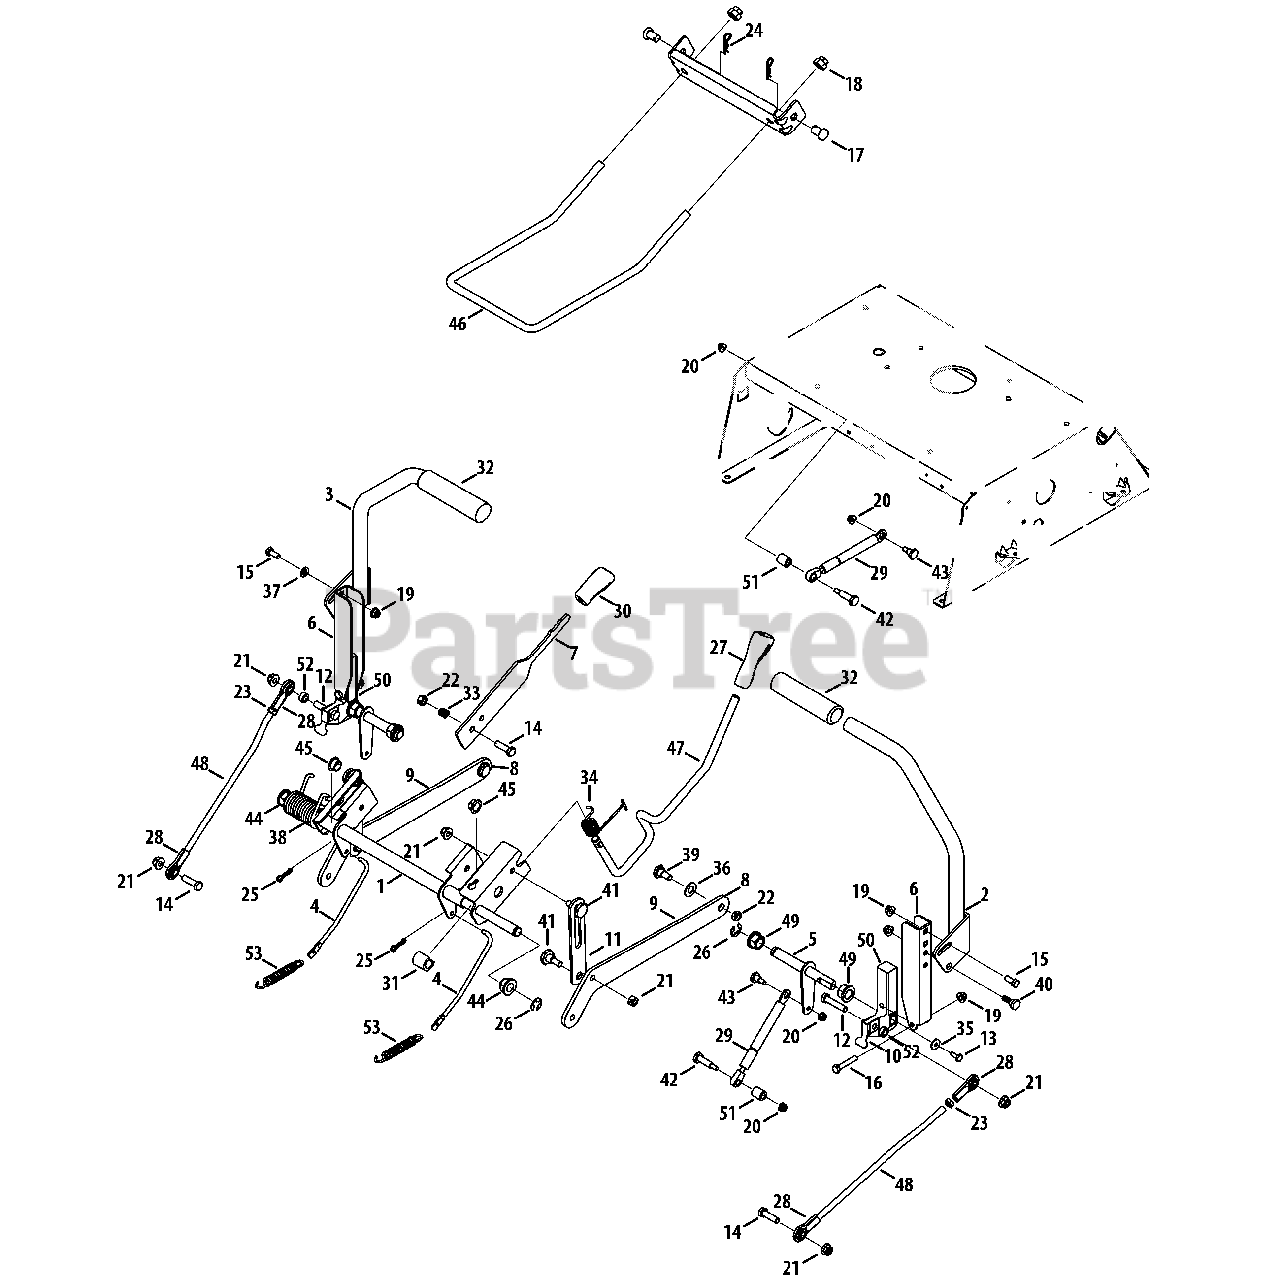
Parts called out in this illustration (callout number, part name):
1	Deck Lift Shaft Assembly
2	Lapbar Lever RH
3	Lapbar Lever LH
4	Brake Rod
5	Control Shaft
6	Lapbar Pivot Bracket
7	Brake Handle
8	Front Deck Hanger Bracket
9	Deck Lift Arm
10	Switch Actuator Bracket
11	Lift Link Plate
12	Hex Screw, 3/8-16 x 1.75
13	Hex Lock Screw, 1/4-20 x .62
14	Hex Cap Screw, 3/8-16 x 1.25
15	Hex Cap Screw, 5/16-18 x .75
16	Hex Cap Screw, 5/16-18 x 1.75
17	Clevis Pin, .50 x .78
18	Hex Nut, 1/2-13
19	Hex Flange Insert Lock Nut, 5/16-18
20	Hex Flange Insert Lock Nut, 1/4-20
21	Hex Flange Insert Lock Nut, 3/8-16
22	Hex Lock Nut, 3/8-16
23	Jam Nut, 3/8-24
24	Bow-Tie Cotter Pin
25	Cotter Pin
26	E-Ring, .625 Dia.
27	Handle Grip
28	Rod End
29	Damper Cylinder
30	Handle Grip
31	Spacer, .62 x 1.0
32	Hand Grip
33	Compression Spring
34	Torsion Spring
35	Bell Washer, .265 x .75 x .062
36	Flat Washer, .51 x 1.0 x .06
37	Flat Washer, .344 x .688 x .065
38	Torsion Spring, LH
39	Shoulder Screw, .498 x .340 x 3/8-16
40	Shoulder Screw, .437 x .268 x 5/16-18
41	Shoulder Screw, .5 x .434 x 3/8-16
42	Shoulder Screw, .374 x 1.16 x 1/4-20
43	Shoulder Screw, .375 x .38 x 1/4-20
44	Hex Flange Bearing
45	Flange Bearing, .626 x .938 x .344
46	Deck Front Hanger Rod
47	Deck Lift Handle Rod
48	Lapbar Control Rod
49	Hex Flange Bearing
50	Control Hub
51	Spacer, .385 x .630 x .75
52	Spacer, .380 x .625 x .265
53	Extension Spring, .59 x 4.00
